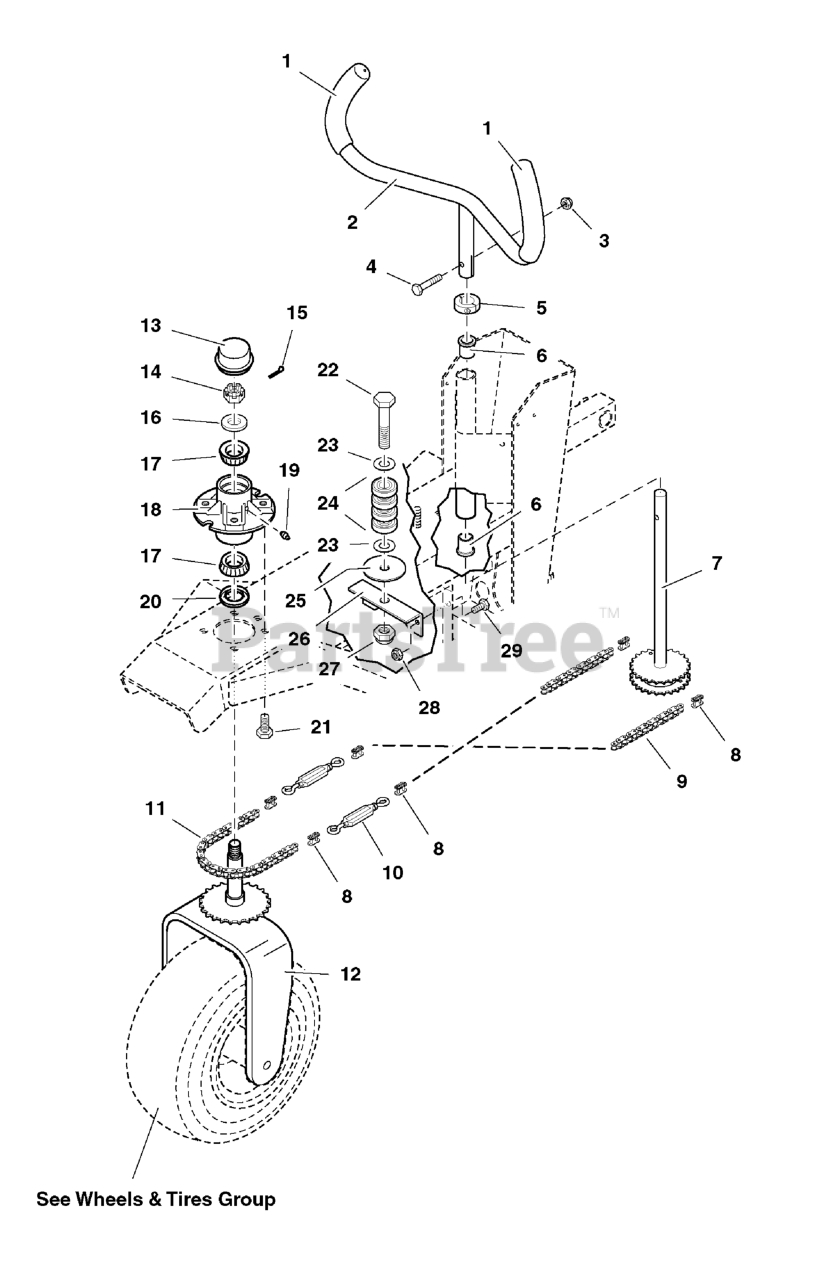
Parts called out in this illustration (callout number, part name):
1	GRIP, Foam
2	STEERING HANDLE
3	NUT, 3/8-16 HEX NYLON LOCK
4	BOLT, 3/8-16 X 1-1/2" GD5 CZ
5	COLLAR, 1" Split
6	BUSHING, Flange
7	SHAFT, Steering Sprocket
8	CONNECTOR, #40 Chain Link
9	CHAIN, #40 Roller, 31 Links
10	TURNBUCKLE
11	CHAIN, #40 Roller, 35 Links
12	MOUNT, Steering Tire
13	CAP
14	NUT, 3/4-16 Hex Slotted
15	PIN, COTTER, 1/8 X 1-1/4
16	WASHER, 3/4 SAE
17	BEARING, Tapered Roller
18	HUB, Steering
19	GREASE FITTING
20	SEAL, GREASE
21	BOLT, 1/2-20 X 1-1/4" GD5 CZ
22	BOLT, 5/8-11 x 3" GD5 CZ
23	WASHER, 5/8" SAE
24	BEARING, Roller
25	WASHER, Chain
26	MOUNT, Chain Roller
27	NUT, 5/8-11 Hex Jam Nylon Lock
28	NUT, 5/16-18 Hex Nylon Lock
29	BOLT, 5/16-18 X 3/4 GD5
